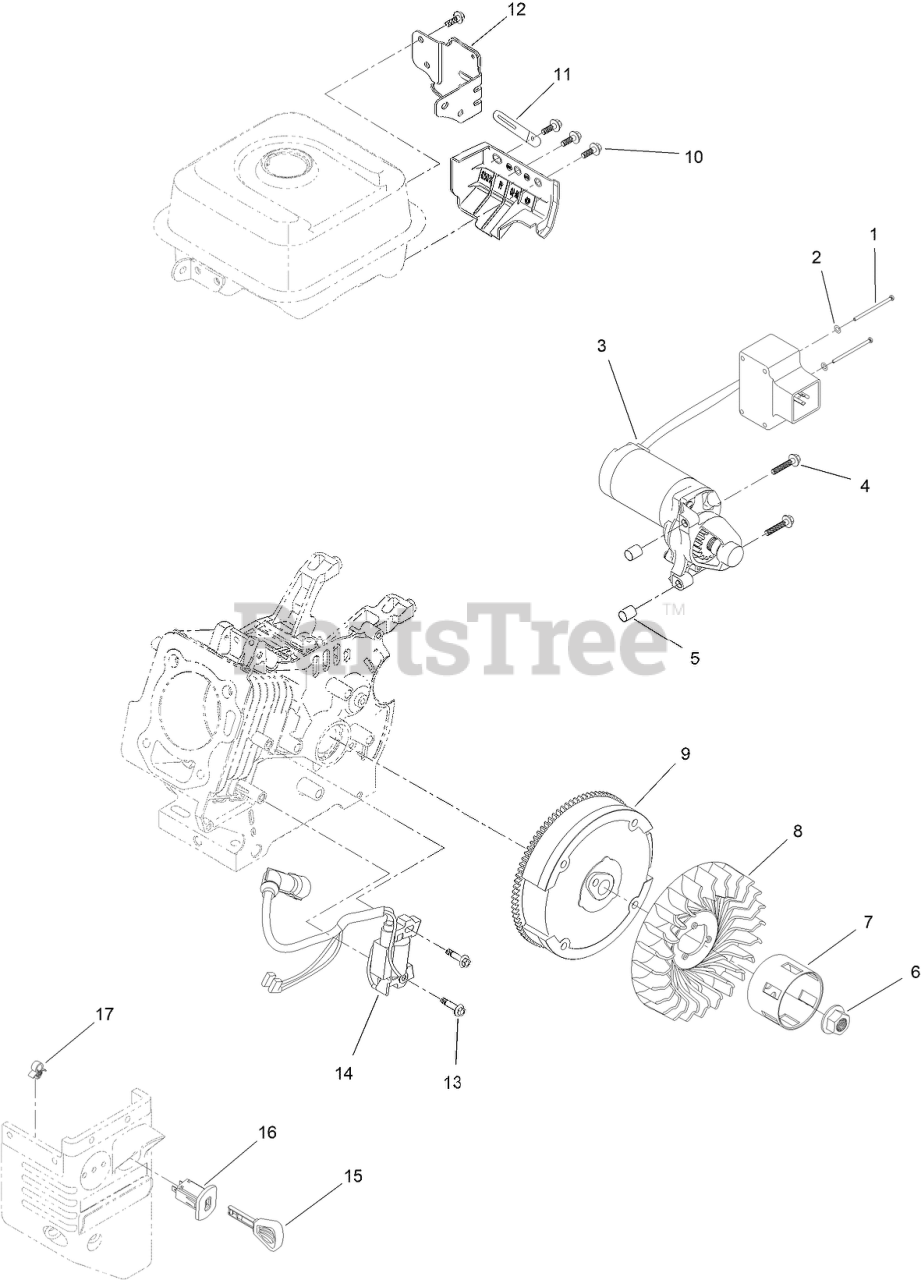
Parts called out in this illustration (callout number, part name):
1	SCREW-BHP
2	WASHER-PLAIN
3	MOTOR-STARTER
4	SCREW-FLANGE
5	PIN-DOWEL
6	NUT-FLANGE
7	CUP-STARTER
8	FAN-COOLING
9	FLYWHEEL AND RING GEAR ASM
10	SCREW-HHF
11	CLIP-HARNESS, WIRE
12	BRACKET-SWITCHBOX, STARTER
13	SCREW-HHF
14	IGNITION COIL ASM
16	SWITCH-KEY
